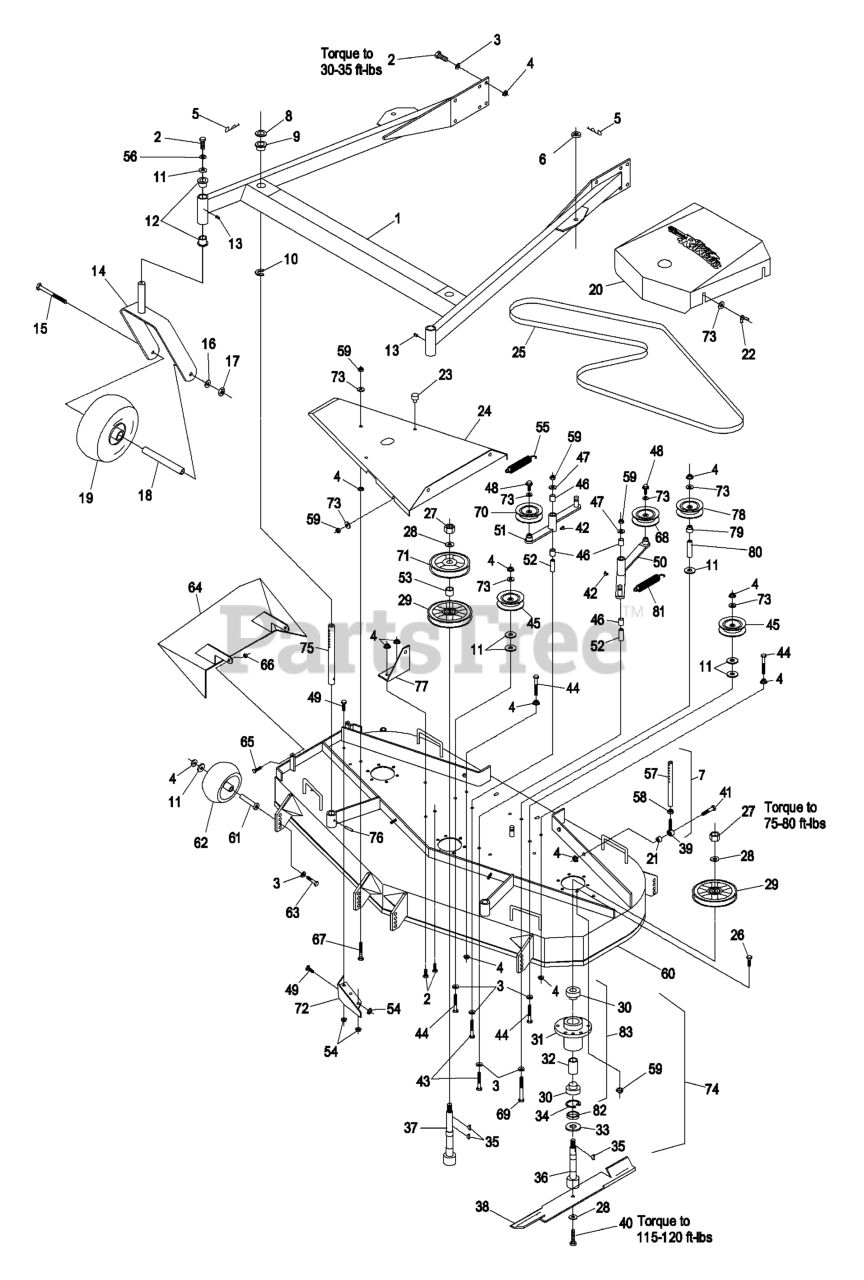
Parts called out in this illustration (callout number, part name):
1	SUPPORT ASSY-FMD60
2	SCREW-HH
3	WASHER-BELLEVILLE
4	NUT-HHF, WHIZ
5	PIN,HAIR COTTER
8	SPACER-DECK SUPPORT
9	BUSHING-DECK
10	RING-RETAINING
11	WASHER
12	BEARING-FLANGED
13	FITTING-GREASE
15	SCREW-HH
16	WASHER-LOCK
17	NUT-HH
22	NUT-WING
24	WLD,DECK COVER
25	BELT-DRIVE, BLADE
26	SCREW-HH
27	NUT-HEX
28	WASHER-SPRING
29	SHEAVE,BLADE DRIVE
30	BEARING
32	SPACER-BEARING
33	GUARD-BEARING, BOTTOM
34	RING-SNAP
35	KEY-WOODRUFF
36	SHAFT,SPINDLE SHORT
39	BALLJOINT
40	SCREW-CAP
41	SCREW-HH
42	FITTING-GREASE, 90 DEG
43	SCREW-HH
44	SCREW-HH
45	IDLER,PULLEY
46	SLEEVE-BEARING
47	WASHER-FLAT
48	SCREW-HHF
49	SCREW-HH
50	Arm, Deck Drive Idler
52	BUSHING-PIVOT, IDLER
53	SPACER-TUBE
55	SPRING-EXTENSION
56	WASHER-LOCK
57	LINK,SUPPORT
58	NUT-HEX
59	NUT-LOCK, NI
61	BUSHING-ROLLER
62	ROLLER-SCALP, ANTI
63	SCREW-HH
65	SCREW-HH
66	NUT-LOCK, NI
68	PULLEY-IDLER
69	SCREW-HH
70	IDLER,PULLEY
72	WLD,BAFFLE DISCHARGE
73	WASHER-FLAT
74	CUTTER HOUSING ASM,OUTER
75	ROD,DECK SUPPORT
77	BRACKET,SPRING ANCHOR
78	PULLEY-IDLER
79	BUSHING,IDLER
80	SPACER-FENDER
81	SPRING-EXTENSION
82	SPACER-PULLEY/BEARING
